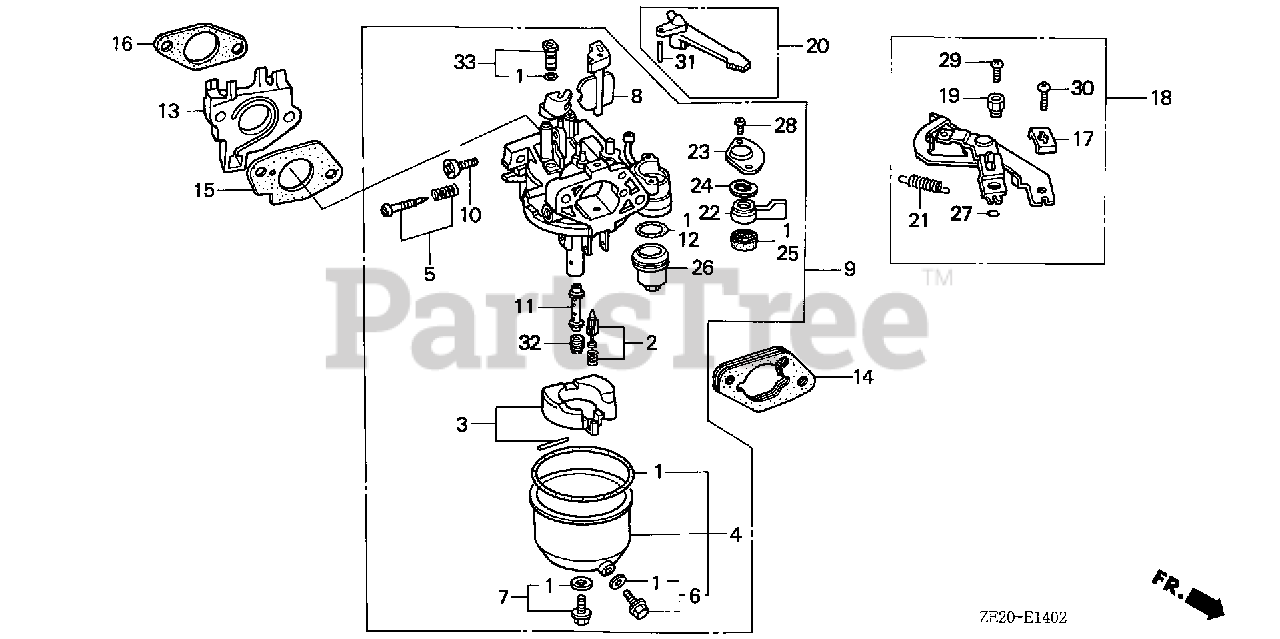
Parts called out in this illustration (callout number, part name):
1	GASKET SET (CARBURETOR NO.)
1	GASKET SET (CARBURETOR NO.) (INCLUDES 16173-001-004)
2	VALVE SET, FLOAT
4	CHAMBER SET, FLOAT
5	SCREW SET, PILOT
6	SCREW SET, DRAIN
7	SCREW SET
9	CARBURETOR ASSY. (BE16A A)
9	CARBURETOR ASSY. (BE16A B)
9	CARBURETOR ASSY. (BE16B A)
9	CARBURETOR ASSY. (BE16B B)
9	CARBURETOR ASSY. (BE16B C) (NOT AVAILABLE)
10	SCREW, THROTTLE STOP
11	NOZZLE, MAIN
12	GASKET, FUEL STRAINER CUP
13	INSULATOR, CARBURETOR
14	SPACER, CARBURETOR
15	GASKET, CARBURETOR
16	GASKET, INSULATOR
17	HOLDER, CABLE
18	STAY ASSY., CHOKE CONTROL (REMOTE)
19	HOLDER, WIRE
20	LEVER, CHOKE (STD)
21	SPRING, RETURN
22	LEVER, VALVE
22	LEVER, PETCOCK
23	PLATE, LEVER SETTING
24	SPRING, PETCOCK LEVER
25	GASKET, PETCOCK (CARBURETOR NO.)
26	CUP, FUEL STRAINER
27	CIRCLIP (5MM)
28	SCREW, PAN (3X8)
29	SCREW, PAN (4X6)
30	SCREW-WASHER (5X16)
31	PIN, SPRING (2X12)
32	JET, MAIN (#88)
32	JET, MAIN (#90)
32	JET, MAIN (#92) (CARBURETOR NO.)
32	JET, MAIN (#95) (CARBURETOR NO.)
